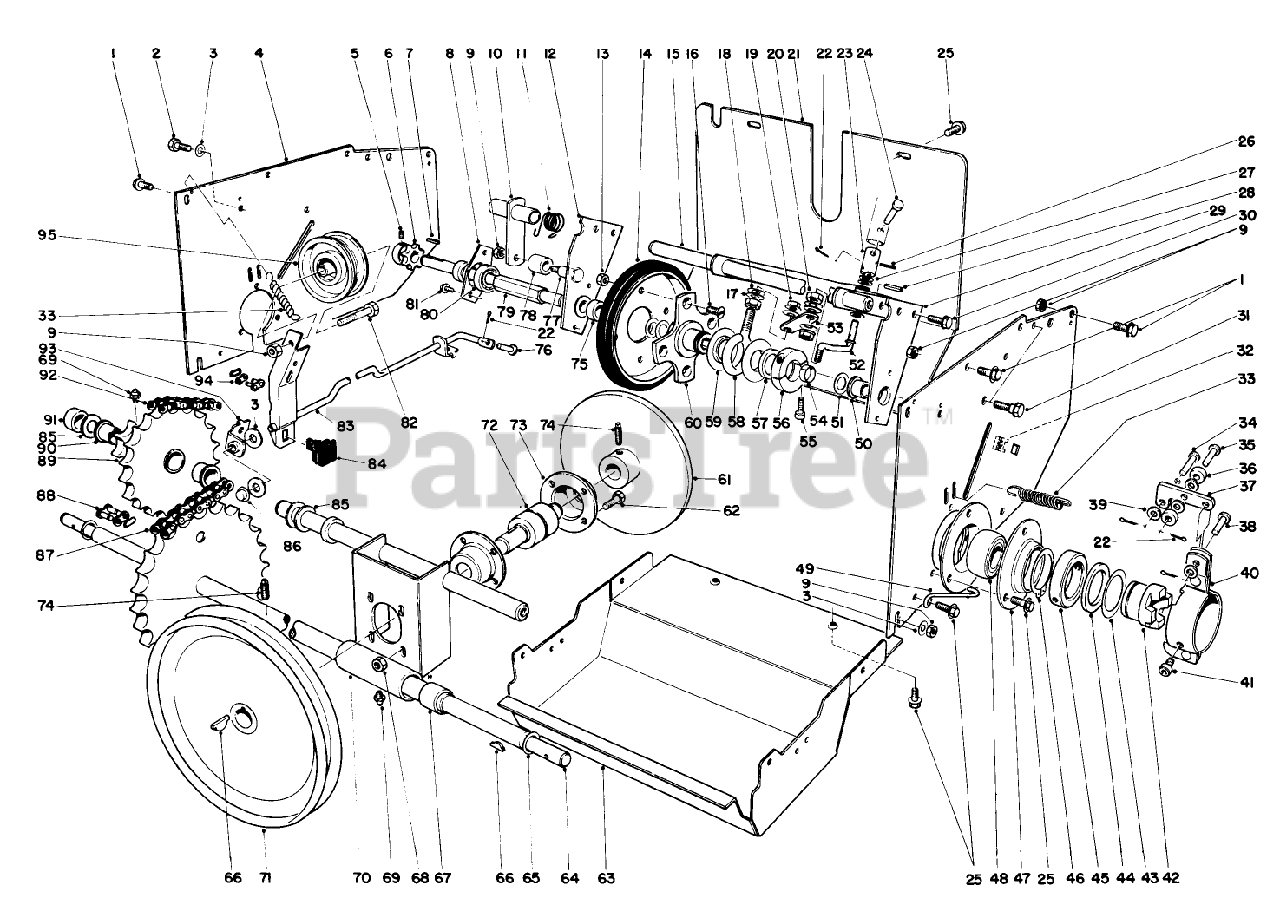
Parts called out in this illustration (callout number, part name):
1	SCREW-HH
2	SCREW-HHFTF
3	WASHER-FLAT
5	SCREW-HSH
6	SPROCKET
8	BEARING CUP
11	TORSION SPRING
14	FRICTION WHEEL
16	SCREW-FH, S
17	WASHER-FLAT
19	NUT-LOCK, FLANGE
21	REAR COVER *R
22	PIN-COTTER
25	SCREW-HWH
26	PIN-SPRING
28	PIN-ROLL
30	SCREW-THD ROLL, HWH
33	EXTENSION SPRING
34	PIN-CLEVIS
35	PIN-CLEVIS
37	CLUTCH CAM ARM
38	PIN-CLEVIS
39	WASHER-FLAT
40	CLUTCH MT BRKT ASM
41	SCREW-HSH
42	WHEEL CLUTCH
43	THRUST WASHER
44	THRUST BEARING
46	RING-RETAINING, EXTERNAL
48	BEARING
50	BUSHING
51	WASHER-FLAT
52	CONNECTION ROD
53	SHIFT ROD PIVOT
55	SCREW-HSH
57	WASHER-THRUST
58	SLIDER RING COLLAR
62	SCREW-HH
63	LOWER SHIELD *R
64	AXLE SHAFT WA
65	WASHER
66	KEY-WOODRUFF
67	BUSHING
68	NUT-KEPS
69	FITTING-GREASE
73	HOUSING BEARING
74	SCREW-SET, SQH
75	SPACER
76	PIN-CLEVIS
77	SHOULDER BOLT
78	Roller-Chain Tensioner
81	SCREW
82	SCREW-HH
85	WASHER-THRUST
88	LINK-CHAIN
89	UPPER SPRKT/ZERK
91	SPACER-IDLER
92	1/4 X 42 CHAIN W/LINK
94	LINK-CONNECTING
95	PULLEY-IDLER
